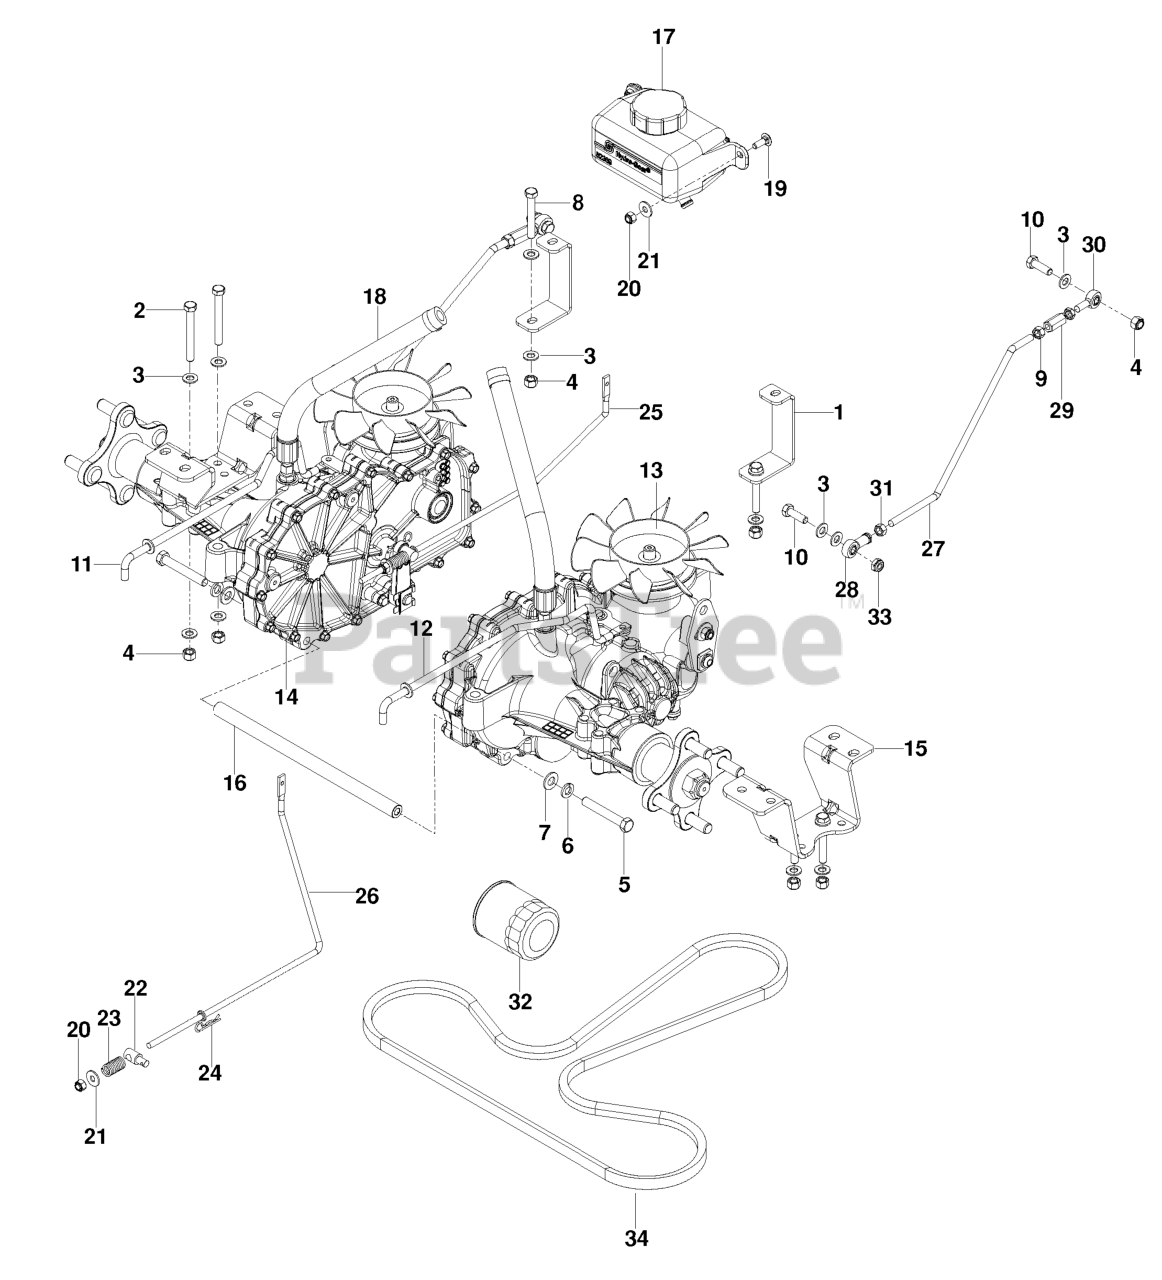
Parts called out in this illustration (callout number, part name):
1	SUPPORT.FRONT.TRANS.BLACK.
2	HCS 5/16C X 2-3/4
3	FLAT WASHER 5/16 SAE
4	NUT 5/16 NYLOC
5	HCS 3/8C X 2 1/2
6	SLW 3/8 STD
7	WASHER 3/8 SAE FLAT
9	NUT 5/16F LEFTHAND
10	HCS 5/16C X 1
11	ROD, BYPASS, RT
12	ROD, BYPASS, LT
13	HG_TRANS, ZT-2800 RT
14	HG_TRANS, ZT-2800 LEFT
15	EZT MOUNT, REAR, BLACK
16	SPACER TUBE, EZT, 11.08
17	HG_EXPANSION TANK W/CAP 71354
19	RHSNB 1/4C X 3/4
20	NUT.1/4-20.HEX.NYLOC.ZD
21	WASHER 1/4 FLAT
22	BRAKE SWIVEL
24	HAIRPIN #2
25	ROD EZT BRAKE LT
26	ROD EZT BRAKE RT
27	ROD, MOTION CONTROL
28	RH ROD END
29	ROD END COUPLER
30	RP.ROD.END.LH
32	HG_FILTER, ZT4800 52114
33	5/16-18 THIN PROF NY
34	BELT, EZT HYDRO
